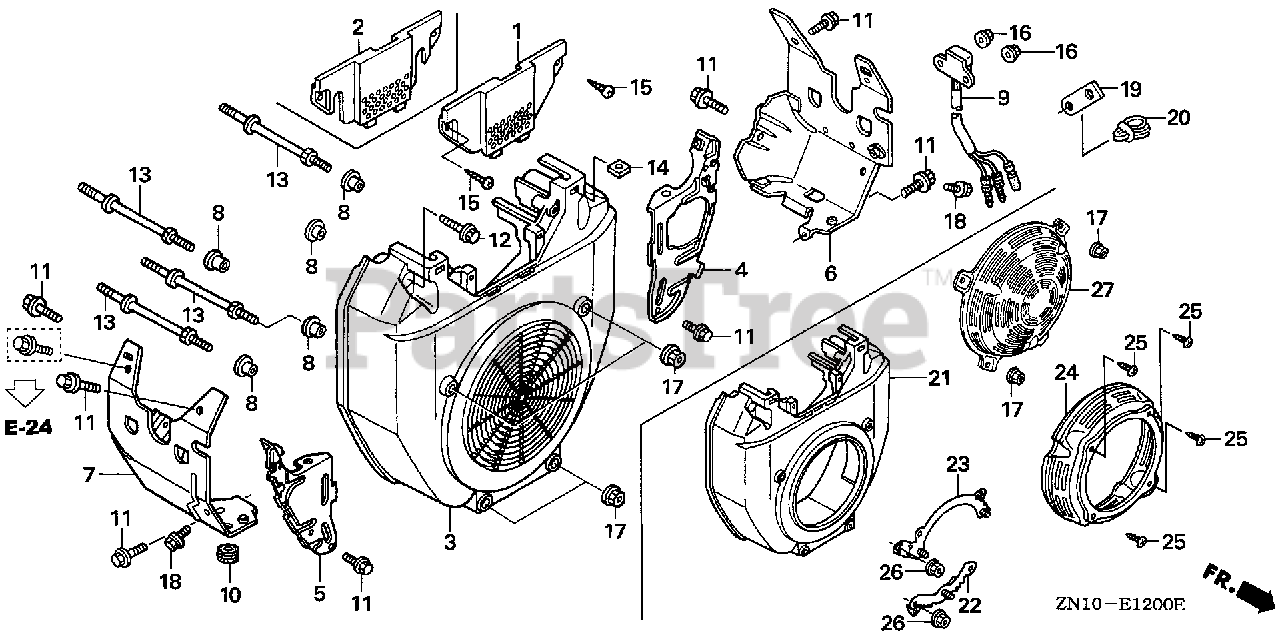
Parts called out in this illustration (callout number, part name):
1	COVER, FUEL PUMP
4	PLATE, SIDE
5	PLATE, SIDE (R. SIDE)
6	SHROUD (OIL ALERT) (L. SIDE)
7	SHROUD (R. SIDE)
8	COLLAR B, TAILLIGHT
9	ALERT UNIT, OIL
10	RUBBER, RR. FENDER CUSHION
11	BOLT, FLANGE (6X12) (CT200)
12	BOLT, FLANGE (6X23)
13	BOLT, STUD (6X71)
14	NUT, SQUARE (5MM)
15	SCREW, TAPPING (5X20)
16	NUT, FLANGE (5MM)
17	NUT, FLANGE (6MM)
18	BOLT, FLANGE (6X8)
19	BRACKET, WIRE HARNESS CLIP
20	CLIP, WIRE HARNESS *NH1L* (BLACK)
